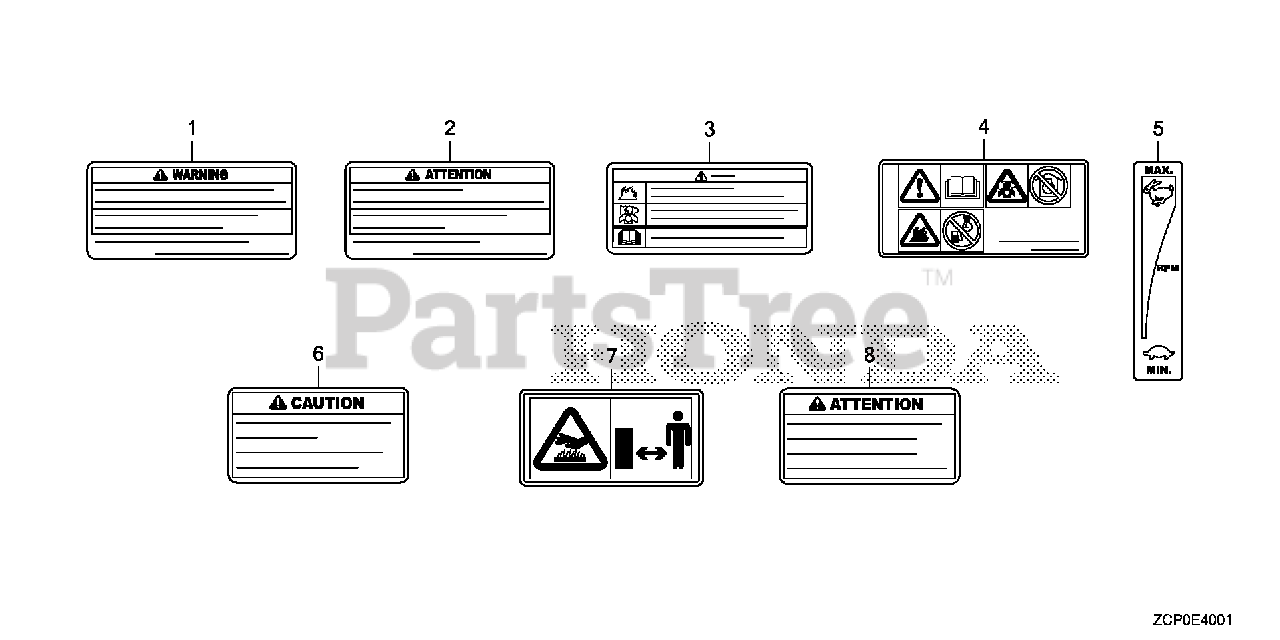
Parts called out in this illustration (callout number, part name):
2	MARK, OPERATOR CAUTION (FRENCH)
4	MARK, OPERATOR CAUTION (PICTOGRAPH)
6	MARK, EX. CAUTION (ENGLISH)
7	MARK, EX. CAUTION (PICTOGRAPH)
8	MARK, EX. CAUTION (FRENCH)
